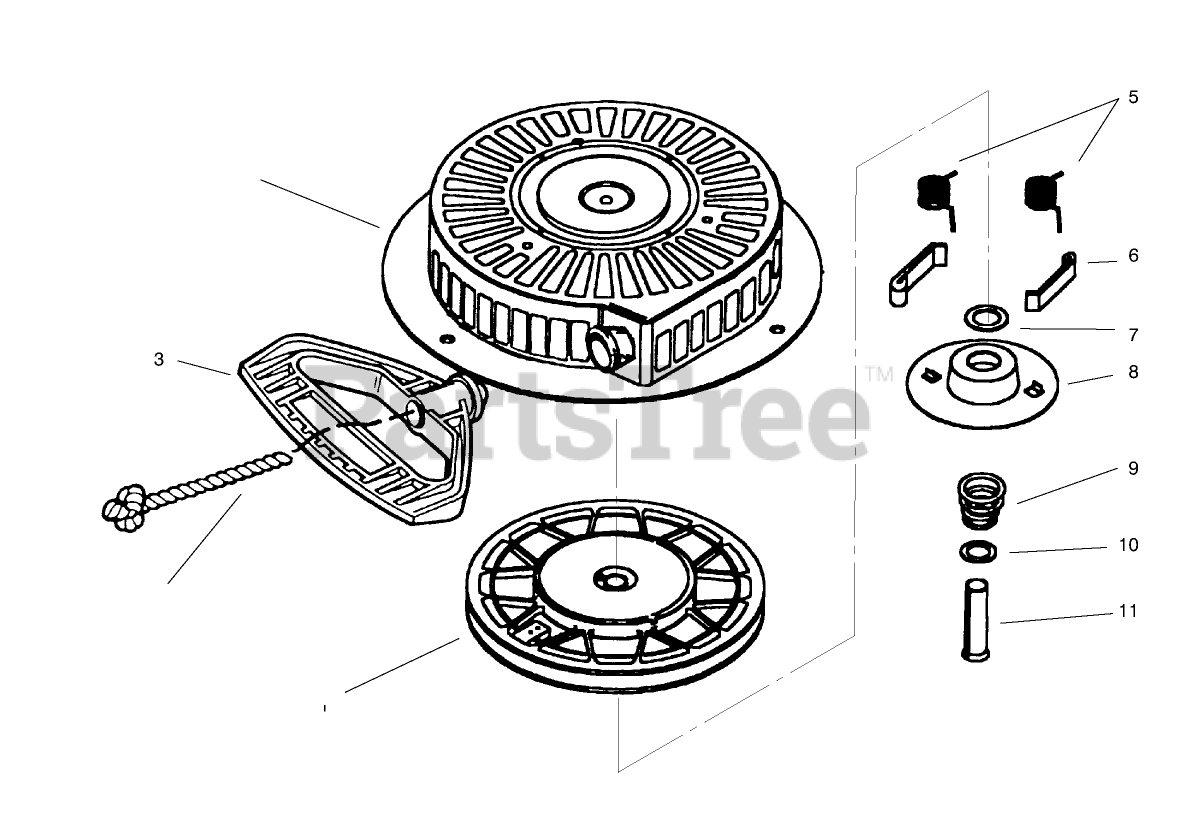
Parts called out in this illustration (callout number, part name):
1	Pulley and Rewind Spring ASM
2	Rope-Starter (98 cut to length)
3	Handle-Starter, Mitten Grip
4	Starter Housing ASM
5	Spring-Dog
6	Dog-Starter
7	Washer
8	Retainer
9	Spring-Brake
10	Washer
11	Pin, Spring (Incl. Ref. #7)
